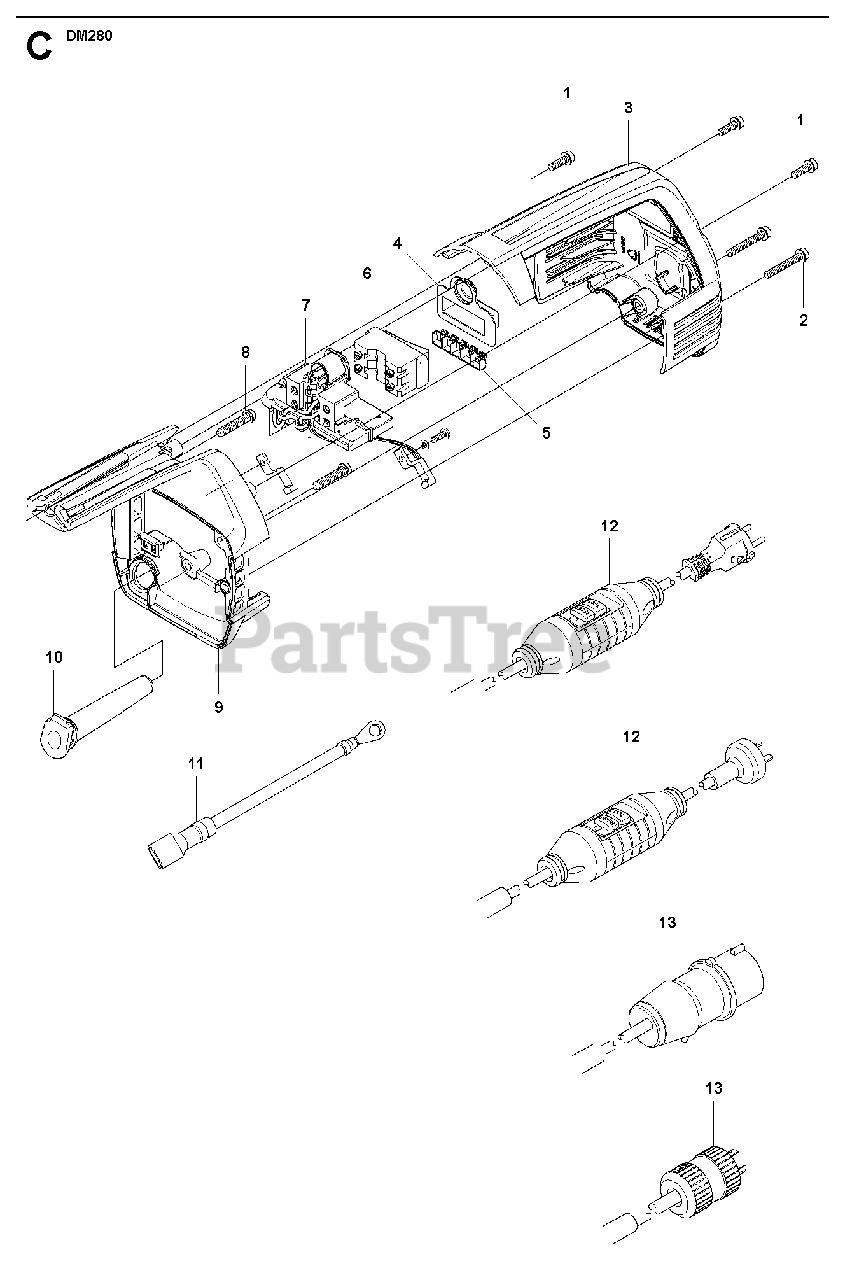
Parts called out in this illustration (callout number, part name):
1	SCREW IHSCFM
2	SCREW IHSCFM
10	CABLE SLEEVE
12	CABLE230V incl PRCD 10mV, EU
12	CABLE230V incl PRCD 10mV, AU
